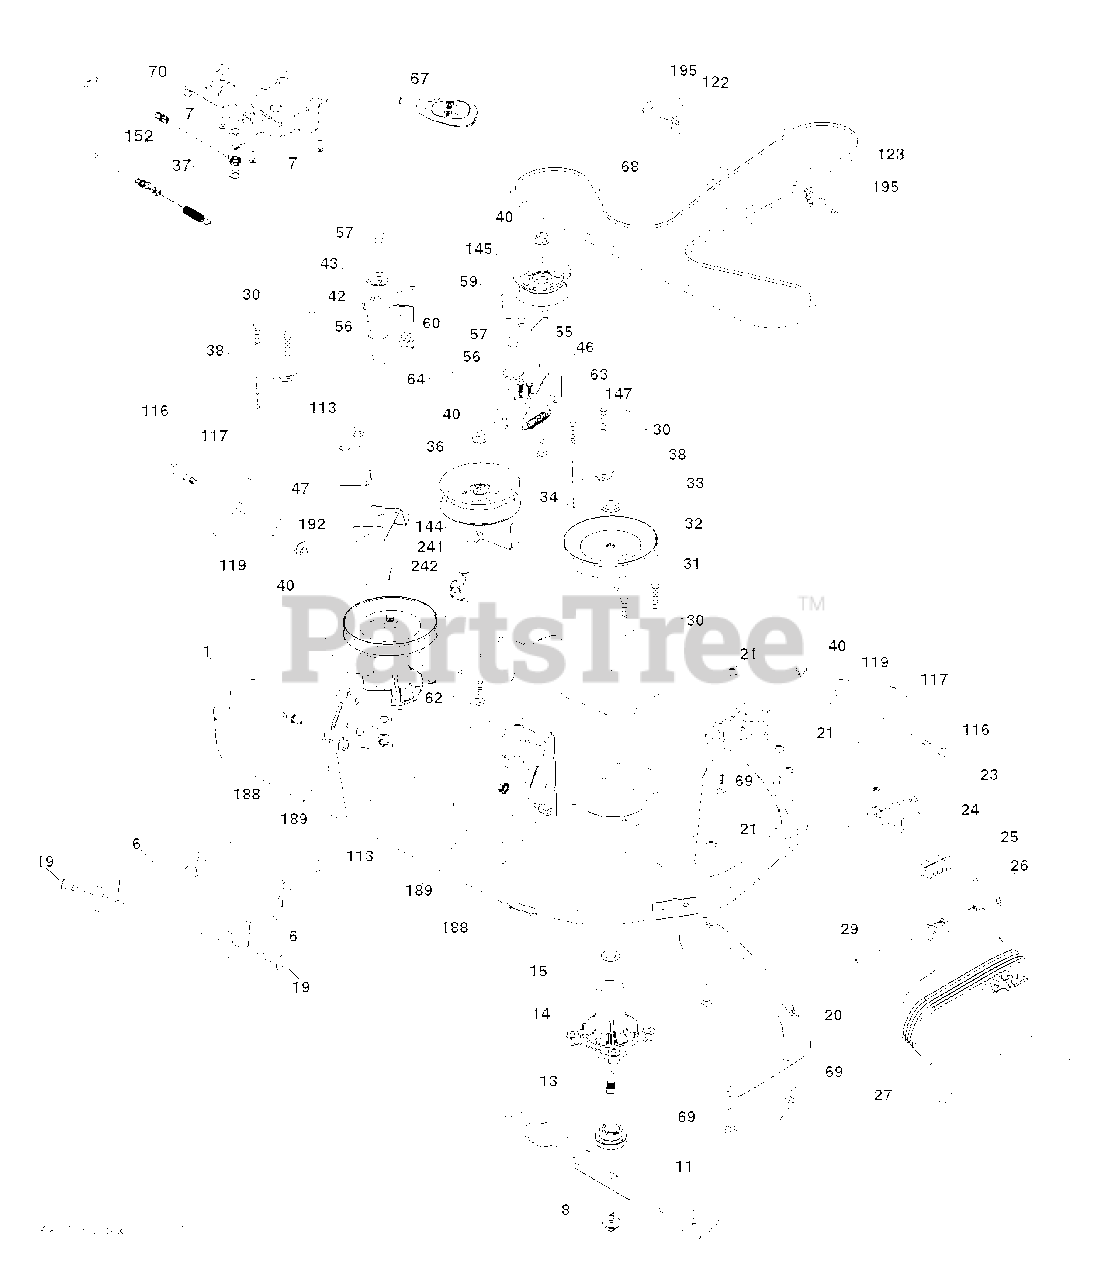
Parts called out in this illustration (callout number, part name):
1	DECK.WELDMENT.42"
6	ARM.SUSPENSION.MOWER.R
7	SCREW.#10 X 0.750.BOS THREAD
8	BOLT.WASHER.ASM.7/16-2
11	42" HI-LIFT BLADE
13	SHAFT.ASM.MDRL.N/GREASE.38
14	HOUSING MANDREL
19	BOLT.SHOULDER
20	BAFFLE.VORTEX
21	LOCKNUT
23	BRKT.DEFLECTOR.38"2005+
24	CAP-SLEEVE LT
25	SPRING.TORSION.DEFLECT
26	NUT PUSH M
27	SHIELD.DEFLECTOR.MOWER.42"BLAC
29	ROD.HINGE
30	SCREW, WASHER HEAD
31	WASHER.SPACER.MANDREL
32	PULLEY.MANDREL.5.438.PD
33	NUT.FLANGE.LOCK.TOP
34	BOLT.3/8-16X1.50
36	PULLEY.IDLER.2006
38	KEEPER.BELT.MANDREL.PULLEY
40	NUT LOCK FLG 3/8-16 UNC
42	SPRING.TORSION.BRAKE
43	SRPING.TORSION.RETAINE
46	SCREW.1/4-20X5/8
47	BRKT.CLUTCH.CABLE
55	IDLER.ARM.42"
56	SPACER.RETAINER
57	SCREW 3/8-16X1
59	GUARD, BELT
60	ARM BRAKE MOWER
62	BOLT
63	ARM BRAKE MOWER
64	LINK BRAKE
67	HANDLE.CLUTCH.CABLE.LT
68	BELT.DECK.DRIVE.42"
69	BOLT
70	CLUTCH.ASM.MANUAL.LT.PRED
113	BOLT.5/16HEX.WHS.HD
117	WHEEL.GAGE.HALF.SPOKED
119	WASHER
122	KEEPER BELT ENGINE LH
123	KEEPER BELT RH
144	KEEPER.BELT.MOWER
145	PULLEY.IDLER.48"PRIMARY
147	RETURN SPRING
152	CABLE.CLUTCH.MANUAL.
188	STUD.FASTNER.W/ANTI-ROTATE
189	NUT LOCK HEX FLANGE 5/16-18
192	BRKT.BRAKE.STAND.LH.
195	SCREW, 3/8-16X3/4
242	PORT.WASHOUT
